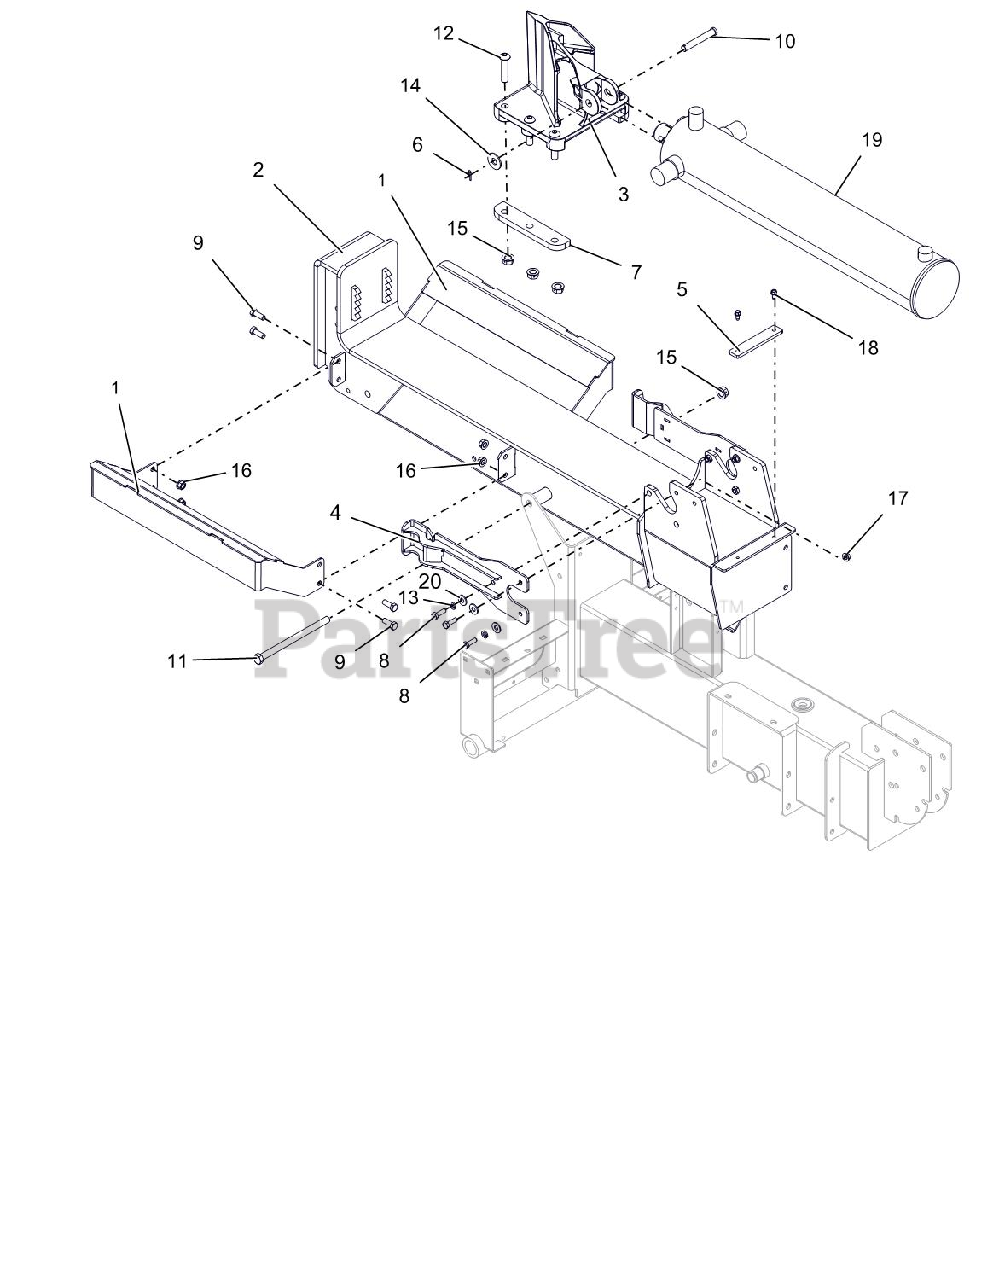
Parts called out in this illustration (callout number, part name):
1	WLDMT, CRADLE, LOG SPLITTER
2	WLDMT, BEAM - 27/34T SPLITTER
3	WEDGE-LOG SPLITTER-MACHINED
4	WLDMT, PLATE - STRIPPER
5	SPACER, CYLINDER
6	CLIP, SPRING
7	RETAINER-WEDGE
8	@BLT-HEX .31-18X1.00 GR5 YWZC
9	@BLT-HEX .38-16X1.00 GR5 YWZC
10	PIN-CLEVIS .500 X 3.250
11	@BLT-HEX .50-13X7.50 GR5 YWZC
12	SCR-SKH .500-13X2.250 BTH YZ
13	WSHR-LK .312X.097 HVY YWZC
14	@WSHR-FL-STL.563X1.38X.109YWZC
15	NUT-LK-CTR-FLG .50-13 YWZC
16	@NUT-LK-TOP-FLG .38-16 YWZC
17	@NUT-LK-TOP-FLG .31-18 YWZC
18	SCR-TAP .25-20X.50 HWH TR YWZ
19	CYLINDER,4.5 W/DECALS
20	@WSHR-FL-STL.38X.875X.083 YWZC
